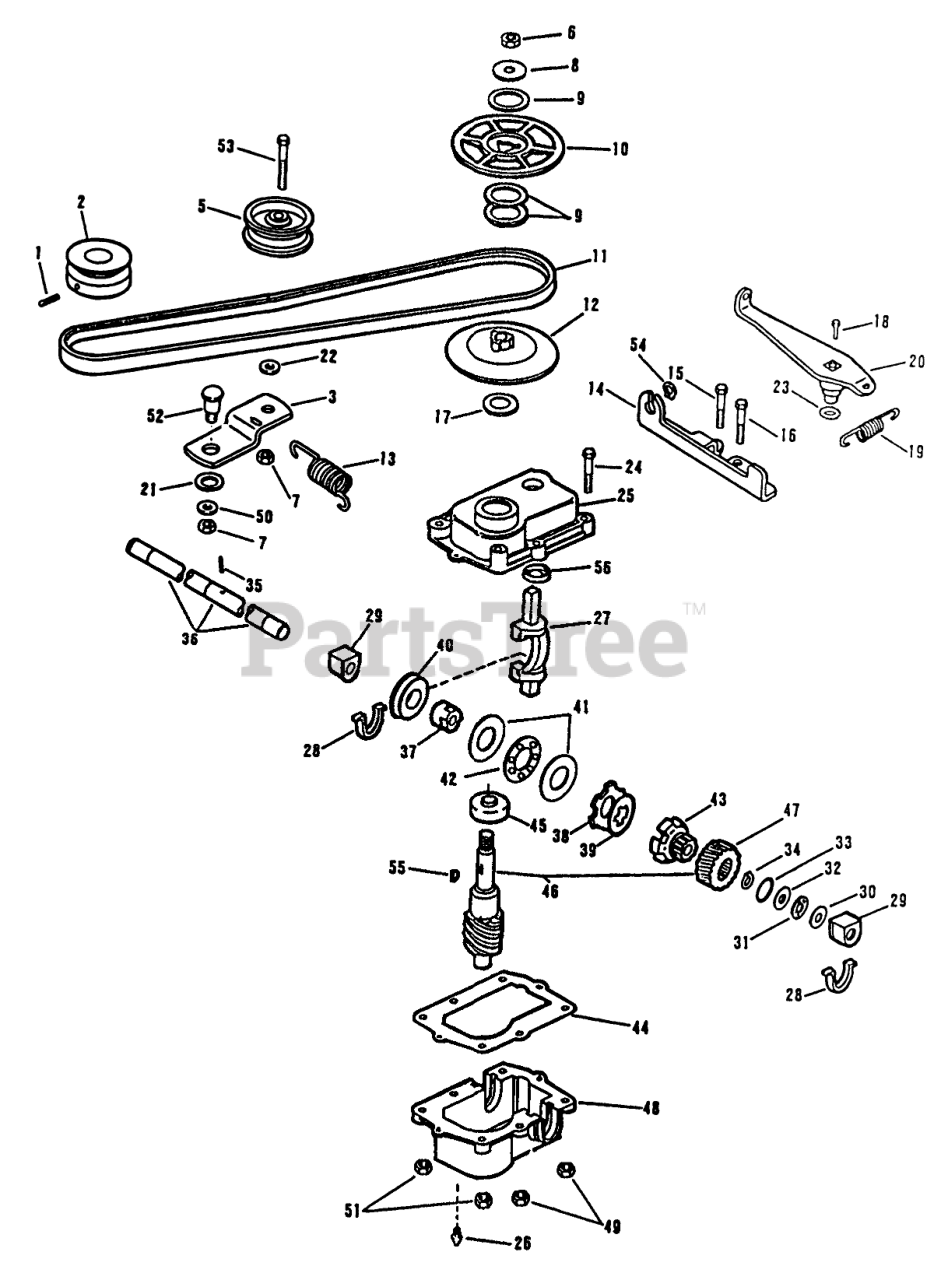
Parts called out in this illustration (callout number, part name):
1	SET SCREW F
2	PULLEY F
3	ARM IDLER LB
4	SCREW
5	PULLEY IDLER NHI
6	NUT-JAM, LOCKING
7	NUT
8	WASHER
9	WASHER
10	PULLEY UPPER PL
11	V-BELT F
12	PULLEY LOWER PL
13	SPRING-EXT.
14	BRACKET CABLE LB
15	SCREW
16	SCREW - CAP
17	WASHER
18	SCREW SEMS SM
19	SPRING
20	SHFT ARM&HUB STA
21	WASHER
22	WASHER S
23	O-RING
24	SCREW
25	Gearcase-Upper
26	PLUG
27	FORK SHIFT
28	PACKING MICH RUB
29	BEARING & SEAL AY (12)
30	THRUST WASHER
31	Bearing-Thrust
32	WASHER-THRUST
33	WASHER
34	RET RING
35	PIN DRIVE LOCK
36	SHAFT - DRIVE
37	SLEEVE ALLEGHENY
38	Driver Plate
39	Driven Plate
40	Collar
41	Thrust Washer
42	Bearing
43	DRIVER BROCKWAY
44	GASKET HOOSIER
45	BEARING
46	WORM WHEEL & SHAFT
47	WORM WHEEL
48	GEAR CASE
49	LOCKNUT E
50	WASHER
51	LOCKNUT E
52	BOLT SHOULDER -700964
53	SCREW
54	RET. RING
55	KEY GALGER
56	GUIDE ELCO
